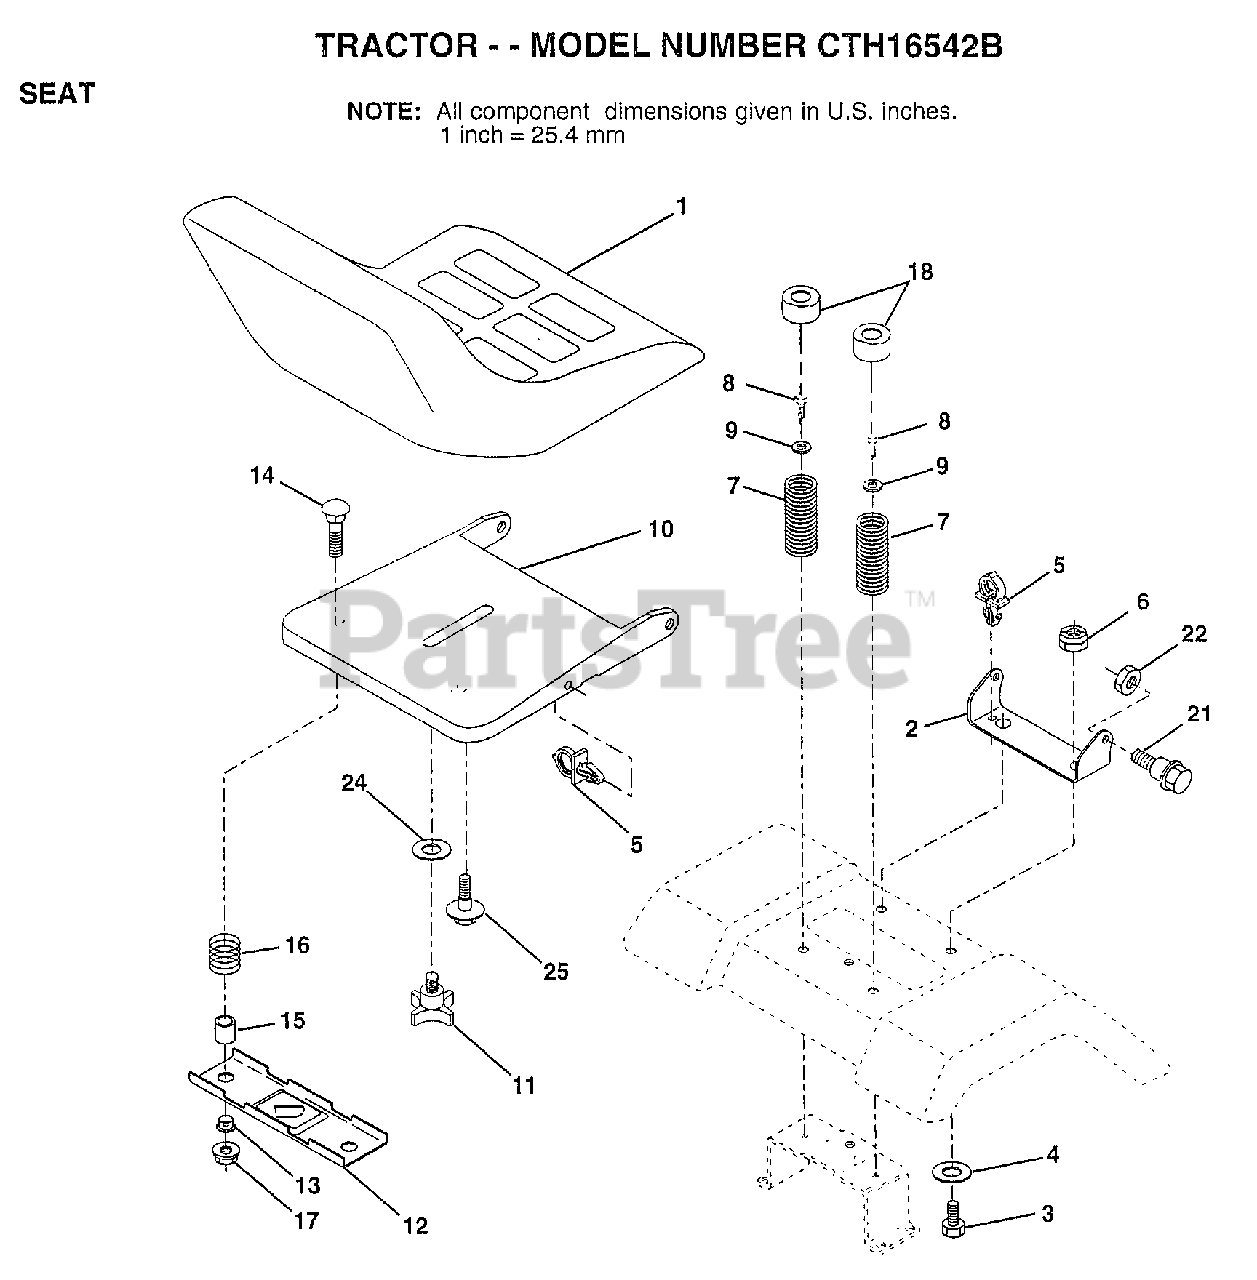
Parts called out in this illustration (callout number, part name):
2	BRACKET PVT SEAT
3	BOLT
4	WASHER PM
5	CLIP.PUSH-IN.HING
6	NUT
7	SPRING COMPRESSIO
8	SCREW GTV
9	WASHER
10	PAN-SEAT
11	"KNOB 1/2"" YT"
12	BRKT SWITCH
13	BUSHING
14	BOLT-RD HD SQ NK
15	SPACER SPLIT
16	SPRING COMPRESSED
18	CAP SPRING
21	"BOLT,SHOULDER"
24	WASHER
25	"BOLT,SHOULDER"
